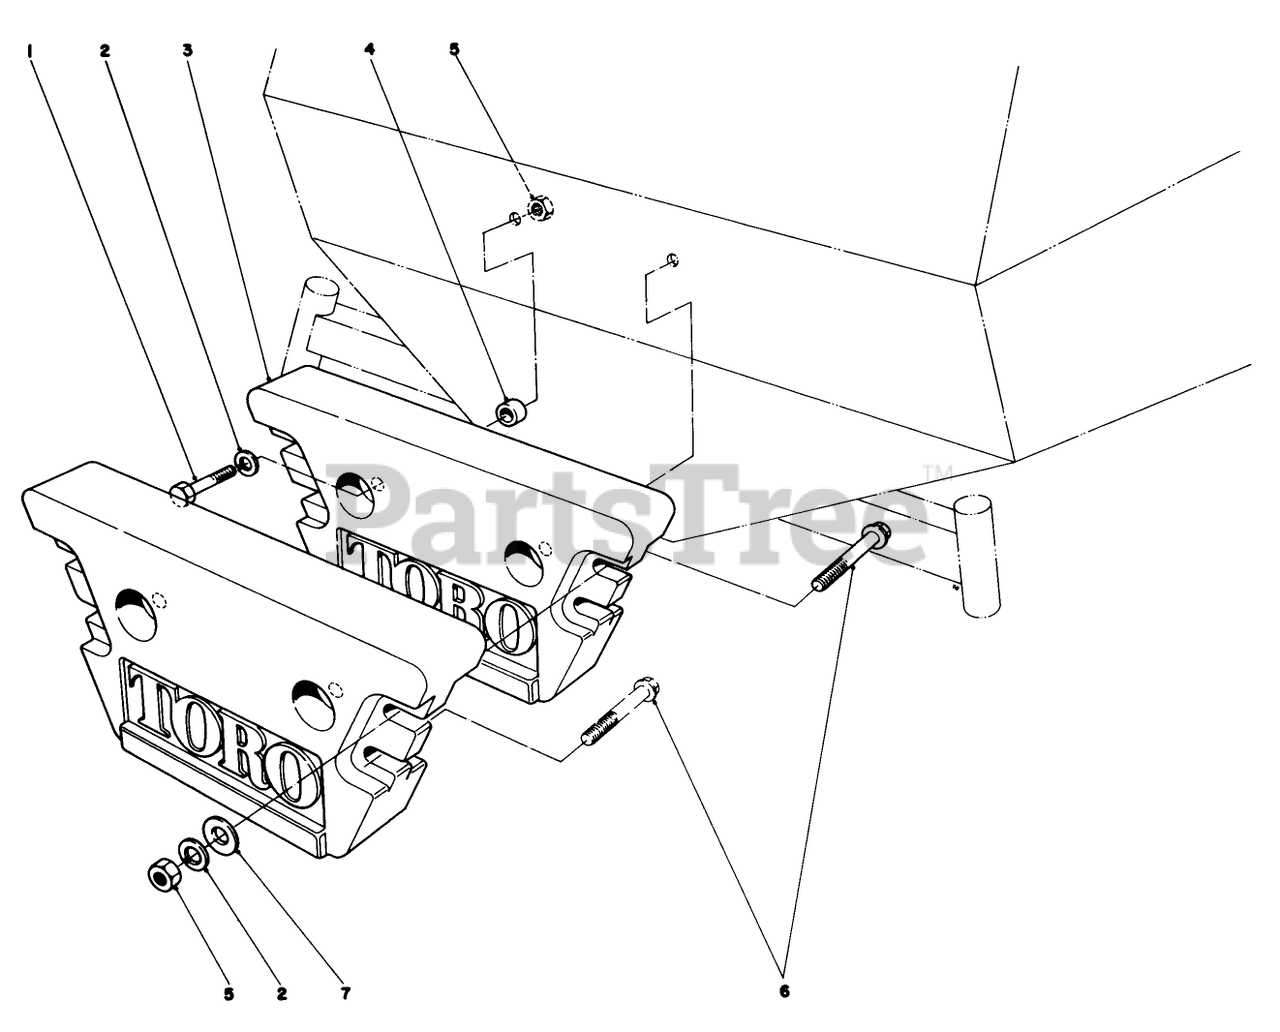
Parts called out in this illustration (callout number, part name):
1	SCREW-HH
2	WASHER-LOCK
3	WEIGHT-REAR
4	SPRING ANCHOR BSHG
5	NUT-HH
6	SCREW-HH
7	WASHER-FLAT
